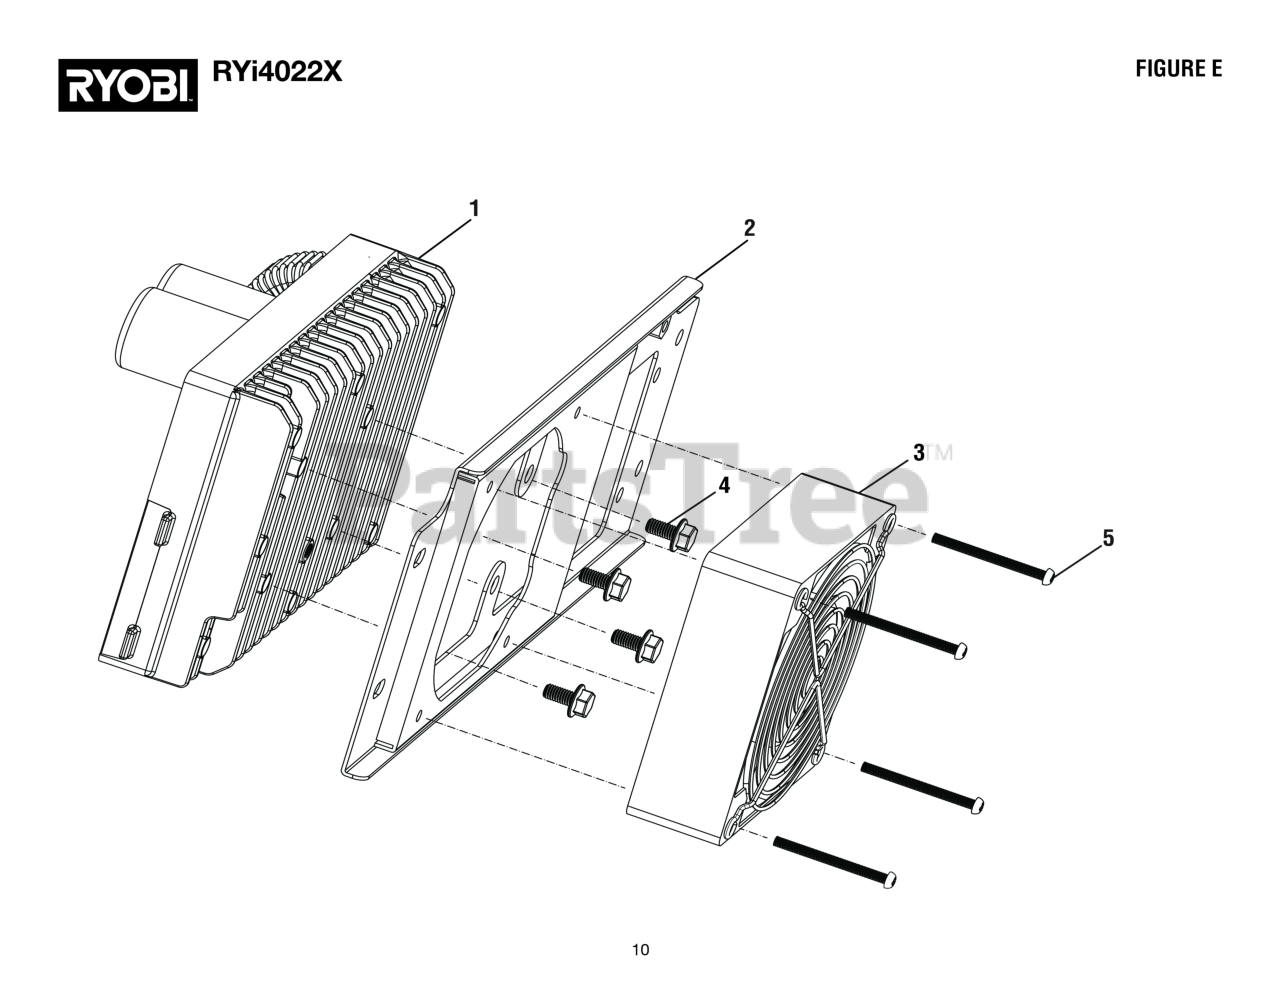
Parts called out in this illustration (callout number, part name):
1	Inverter Module
2	Inverter Module Bracket Assembly
3	AC Cooling Fan
4	Flange Bolt (M6 x 12 mm)
5	Screw (M4 x 46 mm, Pan Hd.)
